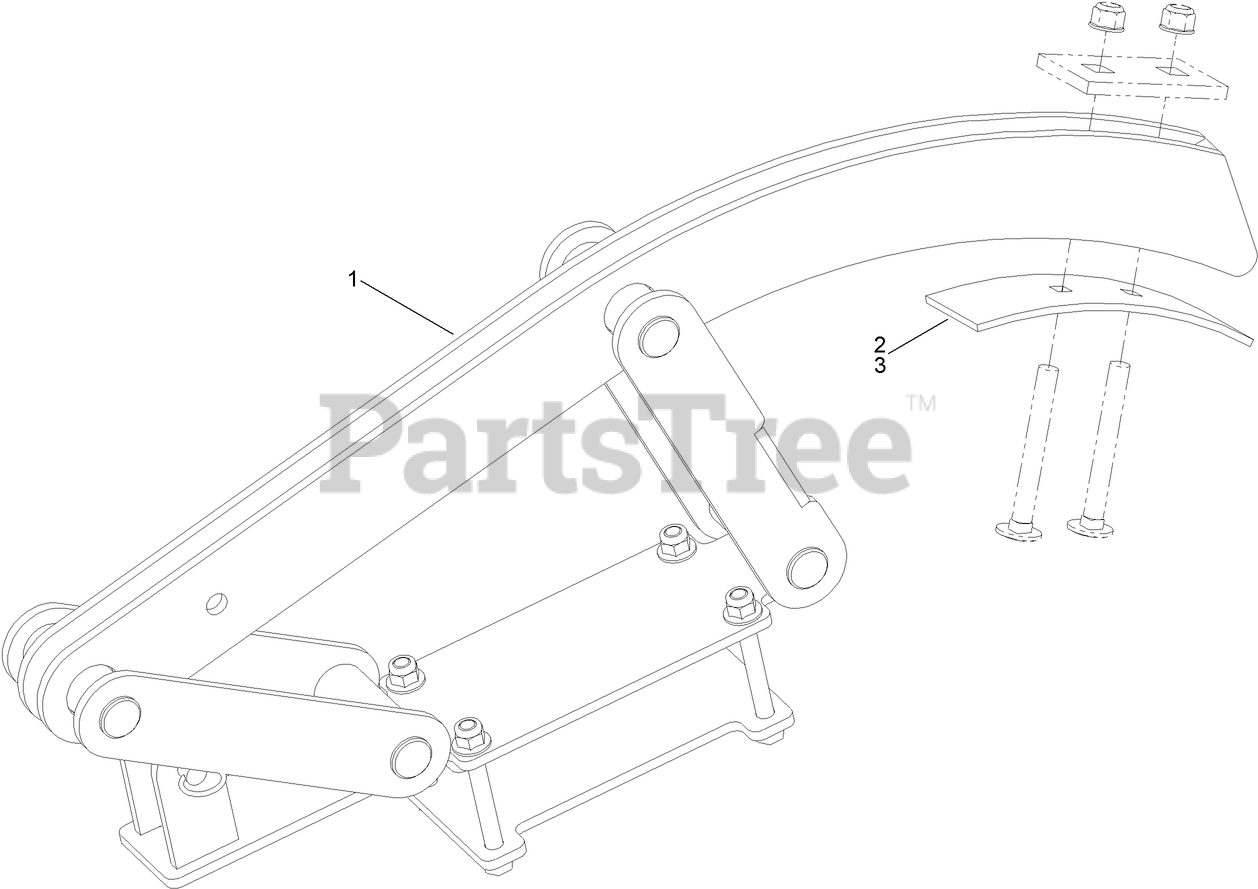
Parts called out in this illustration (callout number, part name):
1	CRUMBER ASM
2	PLATE-CRUMBERSHOE, 4 INCH
3	PLATE-CRUMBERSHOE, 6 INCH
